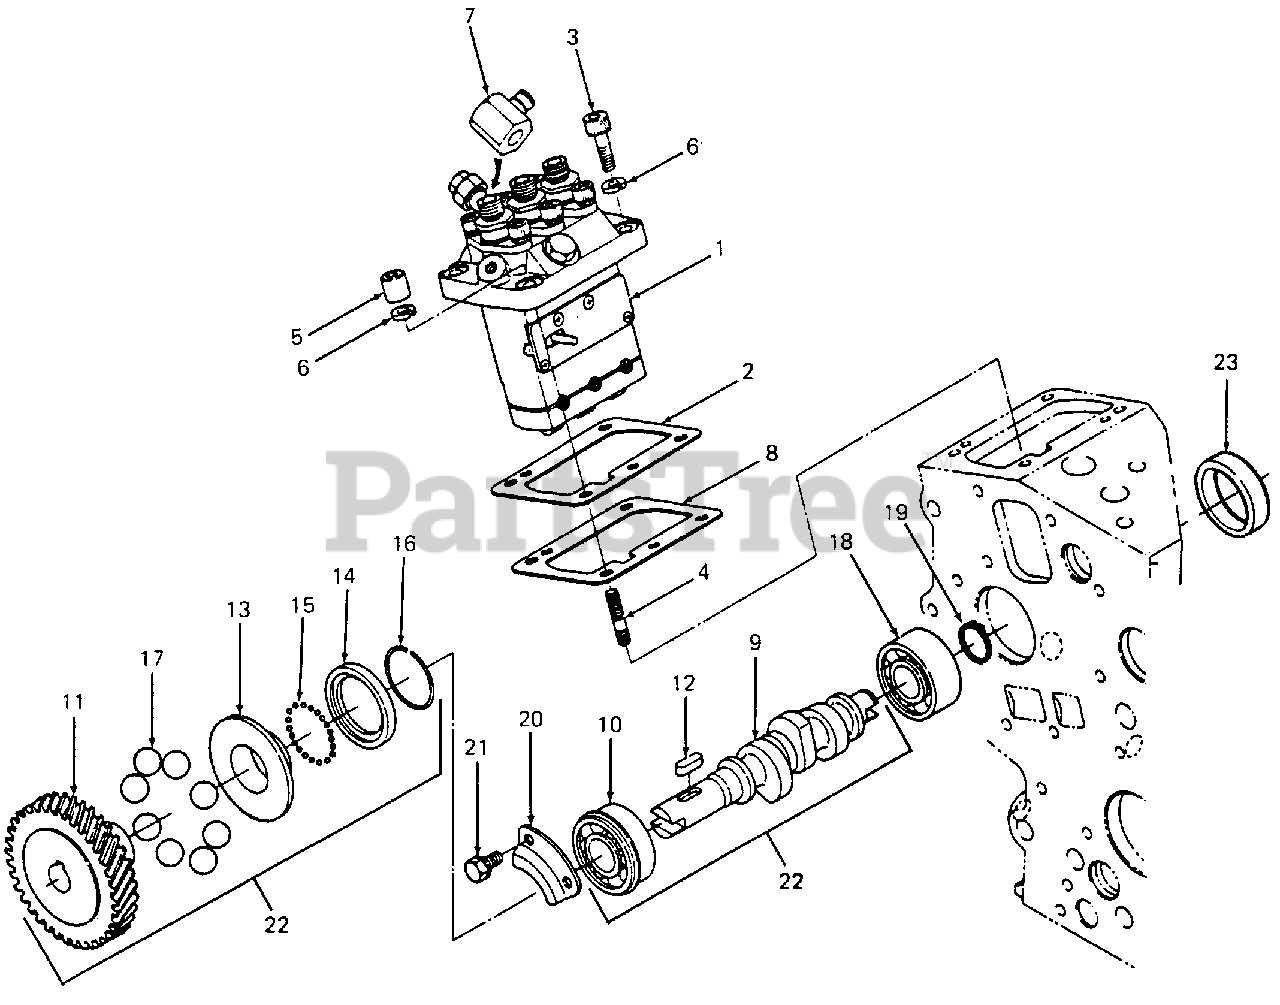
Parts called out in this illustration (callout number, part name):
1	Pump, Injection
2	Shim, Injection Pump
3	Screw, Socket Head
6	Washer, Lock
8	Shim, Injection Pump
9	Camshaft, Fuel Injection
10	Bearing, Ball
11	Gear, Injection Pump
13	Sleeve, Governor
14	Case, Governor Ball
15	Ball, Metal, 1/8 Dia
16	Ring, Governor Sleeve Retaining
17	Ball, Metal, 17/32 Dia
18	Bearing, Ball
19	Ring, External Retaining
20	Stop, Fuel Camshaft
21	Screw, Hex Cap w/Washer
22	Camshaft Assy, Fuel Injection
23	Cover, Camshaft
